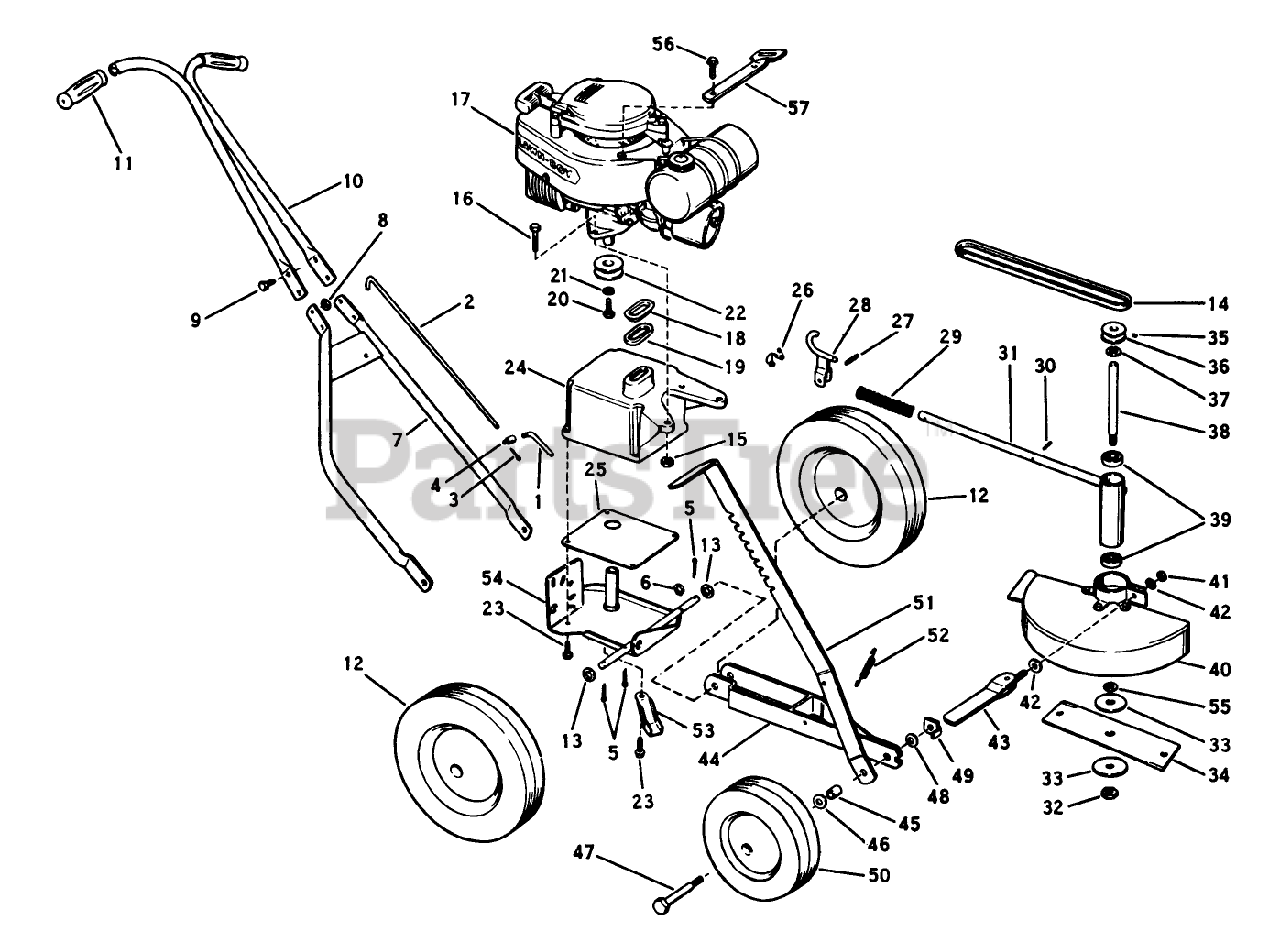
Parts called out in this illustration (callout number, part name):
8	STOP NUT
11	HANDLE GRIP
17	Engine-C-74
19	GASKET S
21	WASHER, LOCK
34	Blade-9"
44	Wheel Bracket and Spacer Assy.
48	WASHER, LOCK
